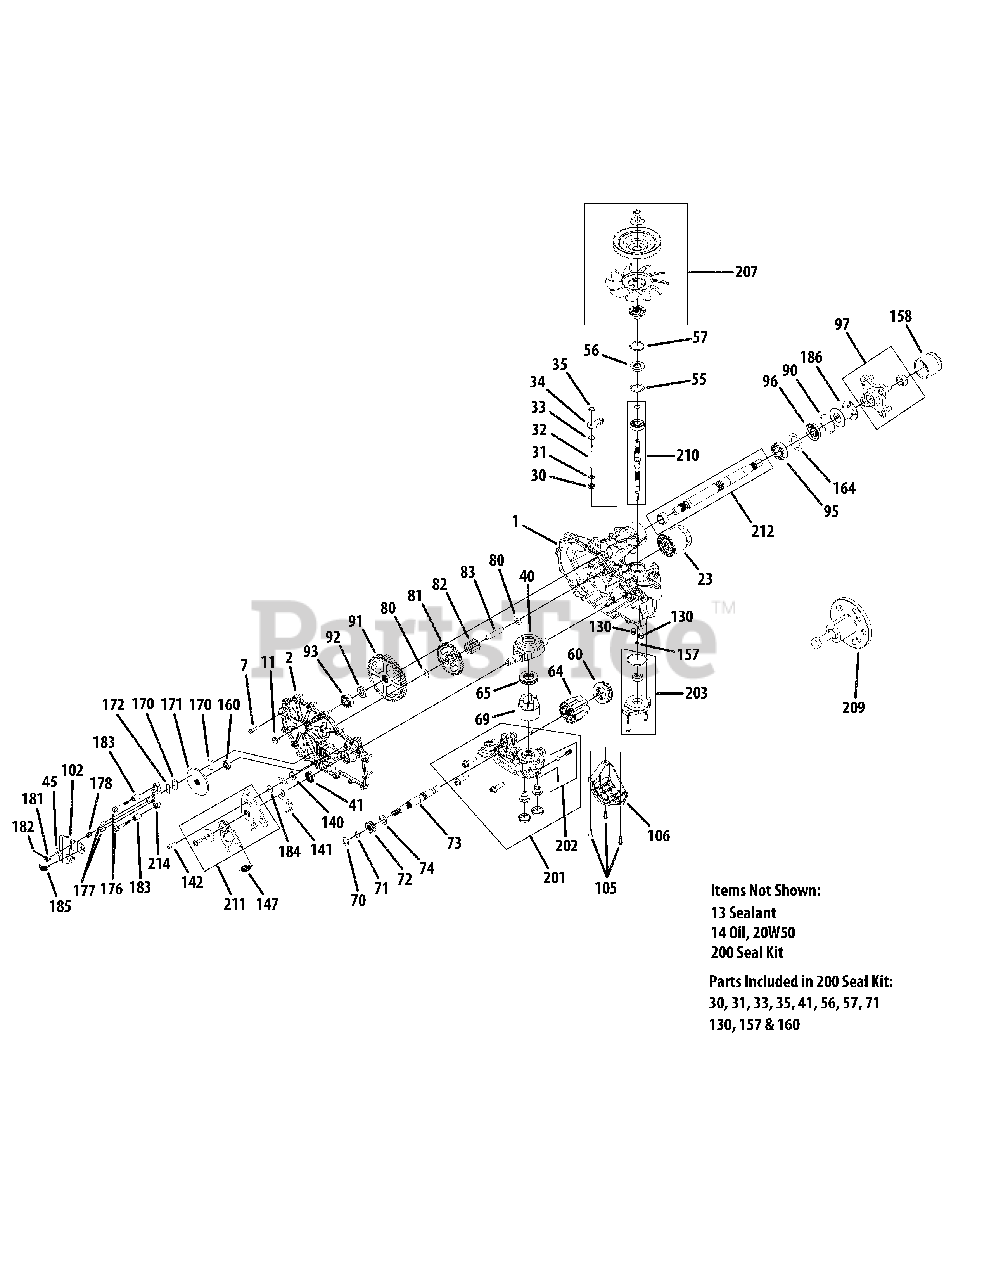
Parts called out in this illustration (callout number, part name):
1	Kit, Main Housing, LH Charge
2	Kit, Cover Side LH Control
7	Screw, Hex Washer
23	Filter, Spin-On 2.6 x 3.0
30	Seal, Lip, .375 x .75 x .25
31	Ring, Retaining .375 External
32	Rod, Bypass
33	Ring Retaining .750 Internal
34	Arm, Bypass
35	Ring, Ret .375 External
40	Trunnion, Swashplate
41	Seal, Lip 18 x 32 x 7
45	Washer, .34 x .88 x .06
55	Washer, 1.23 x 1.57 x .04
56	Seal, Lip 17 x 40 x 7
57	Ring Retaining Internal
60	Bearing, Thrust 35 x 62 x 18
64	Kit, 16cc Cylinder Block Assembly
65	Thrust Bearing, 30 x 52 x 13
69	Kit, Block, 7 Piston
70	Washer, .63 x 1.00 x .05
71	Ring, Reatining, Motor Shaft
72	Gear, 14T (Steel)
73	Shaft, Motor
74	Washer, .71 x 1.16 x .04
81	Gear, 45T
82	Gear, 11T (Steel)
83	Pin, Jackshaft
90	Ring, Retaining 2.25 Internal
91	Gear, 54T
92	Spacer, .750 x 1.00 x .257
93	Bearing, Ball 3/4 x 40mm x 12mm
95	Bearing, Ball 25.4 x 52 x 15
96	Seal, Lip, 1.0 x 2.06 x .38
97	Kit, Hub 4-Bolt
102	Arm, Brake
105	Screw, Hex Washer 1/4-20 x .75
106	Guard, Filter, LH
130	Tube, Charge Triple O-Ring
140	Spacer, .320 x 1.005 x .150
141	Arm, Neutral Right
142	SHCS, 5/16-24 x 7/8 (W/Patch)
147	Spring, Extension
157	Seal, Gerotor .281 x .420 x .160
158	Cap, Axle
160	Seal, Lip .625 x 1.00 x .250
164	Spacer, 1.355 x 2.035 x .021
170	Puck, Brake
171	Rotor, Brake
172	Puck, Plate
176	Screw .250-20 x 2.0 HFS Patch
177	Pin, Brake Actuating
178	Compression Spring
181	Nut, Castle 5/16-24
182	Pin, Cotter 3/32 x 3/4
184	Washer, .34 x .88 x .06
185	Spring, Brake Arm Bias
186	Tube, Axle 2.03
200	Kit. Seal, ZT-2800
201	Kit, Center Section LH Charge
202	Kit, Charge Relief
203	Kit, Charge
207	Kit, Fan Pulley
207	Fan Only
207	Pulley Hub
209	Kit, Hub Puller
210	Kit, Input Shaft
211	Kit, RTN Bidirectional
212	Kit, Shaft Axle
214	Kit, Brake Yoke
